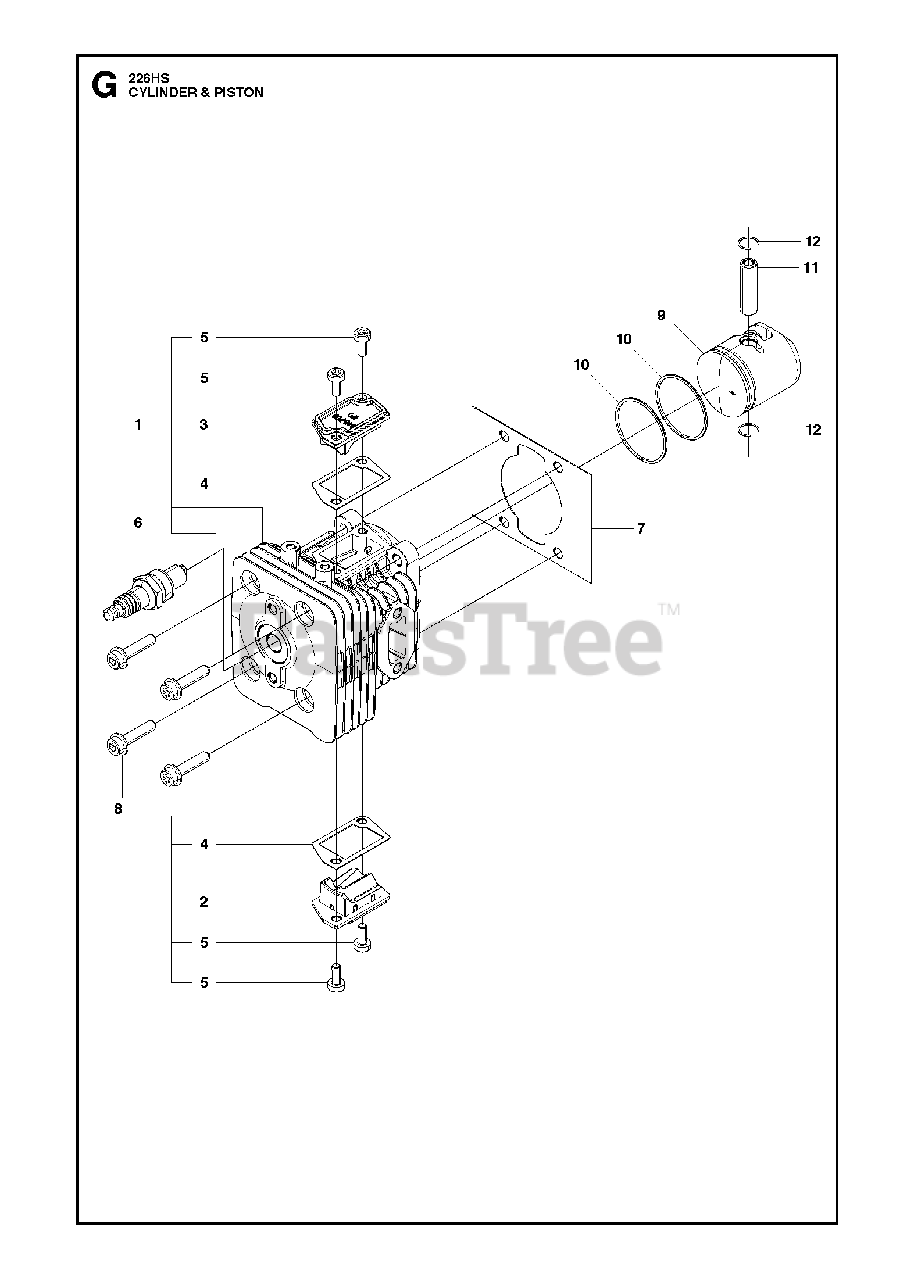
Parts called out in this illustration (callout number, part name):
1	CYLINDER COMPLETE
2	COVER TR(S)
3	COVER TR(F)
4	GASKET, TR
5	BOLT
6	SPARK PLUG NGK CMR7H
7	GASKET, BASE
